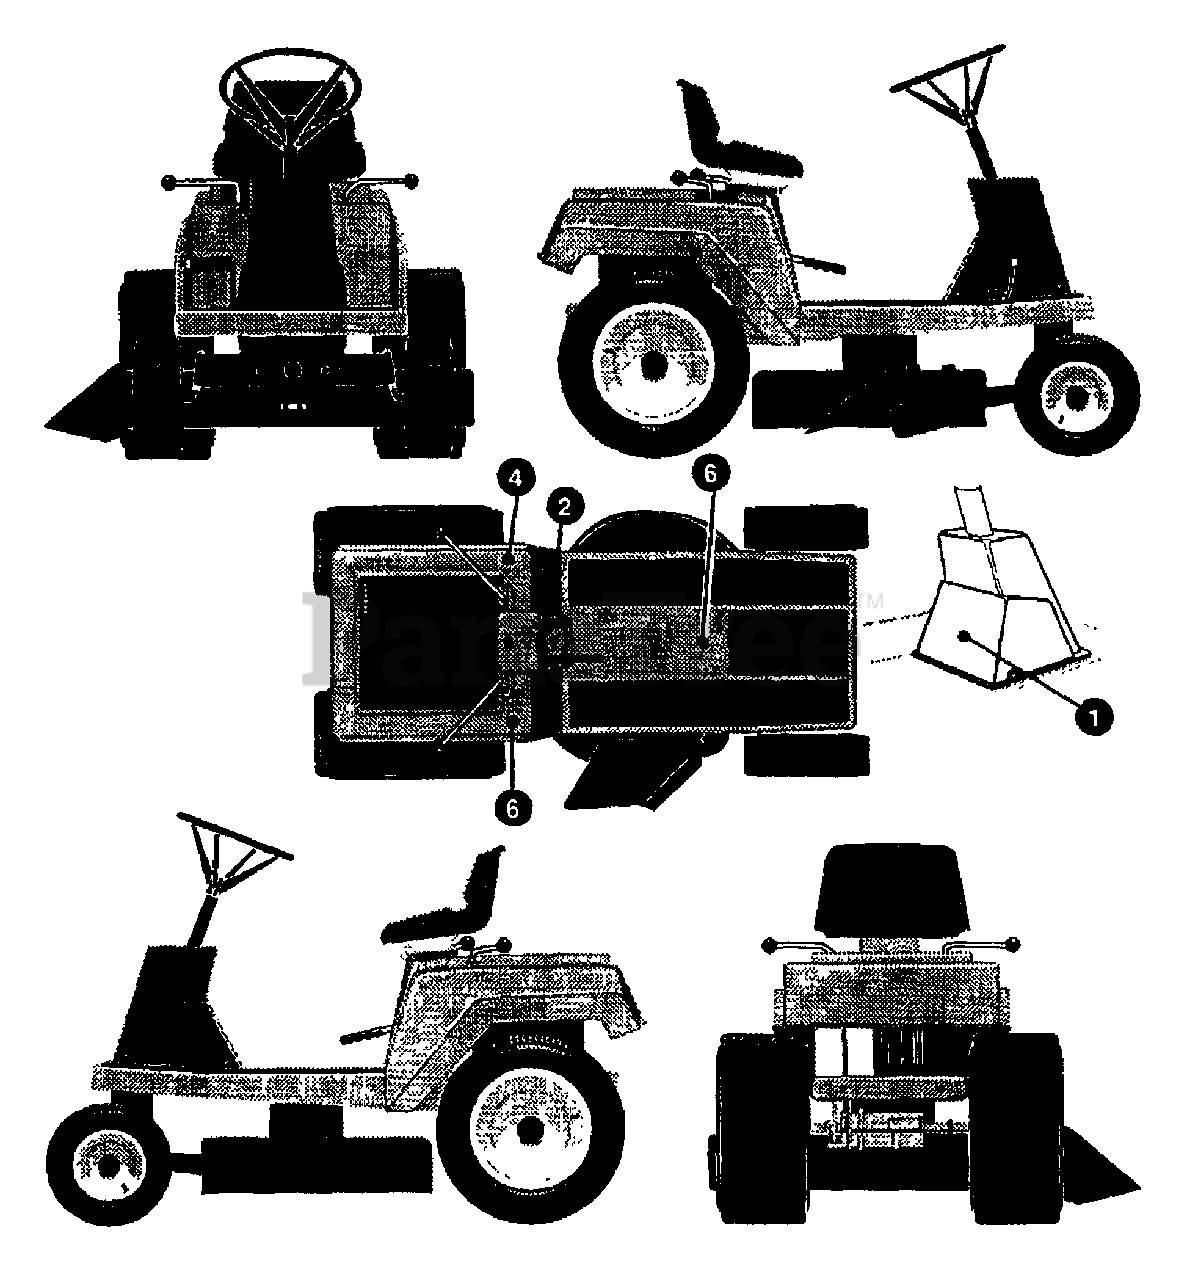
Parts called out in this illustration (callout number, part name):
1	DECAL INSTR. CONSOLE REAR
2	DECAL, CONTROL 30", NO LIGHT
3	DECAL, SHIFI;SSP,ISO,DOM.
4	DECAL,PTO ENGAGEMENT, ISO
5	REFERENCE ONLY
6	DECAL,CONSOLETOP CAUTION NOTE
